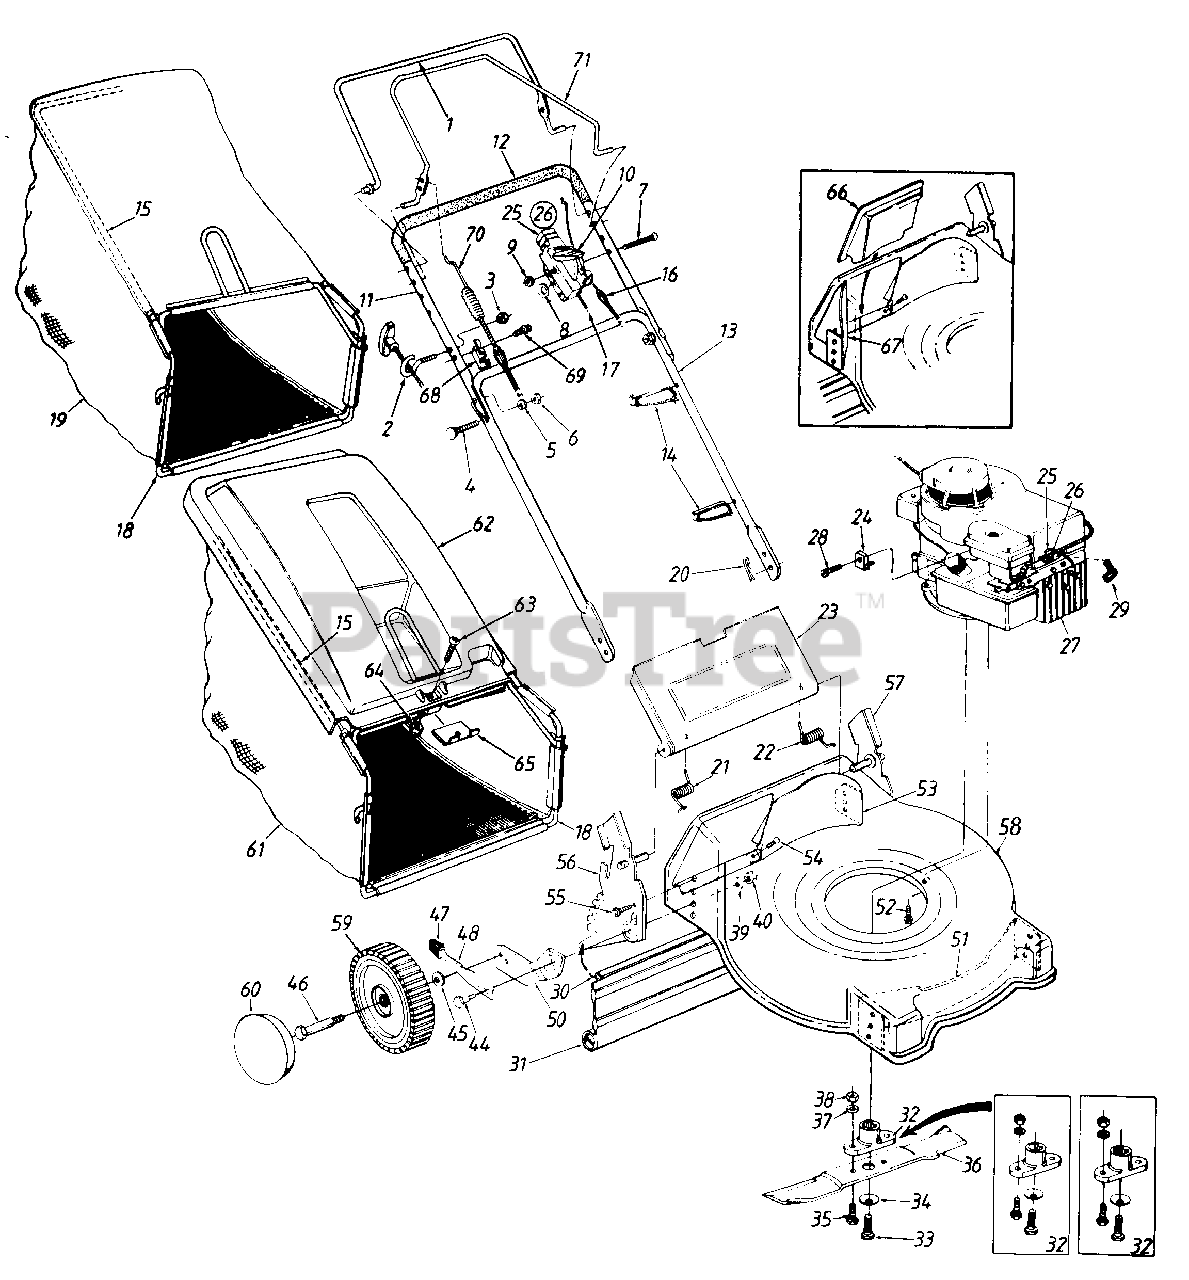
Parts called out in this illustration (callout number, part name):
2	Rope Guide Bolt
3	Hex L-Nut 1/4-20 Thd.
4	Curved Carr. Bolt 5/16-18 x 1.38" Lg.
5	L-Wash. 5/16" I.D.
6	Hex Nut 5/16-18 Thd.
7	Oval C-Sunk Mach. Scr.
8	Spr. Wash..66" I.D.
9	Hex L-Nut 1/4-20 Thd.
10	Throttle Lever
13	Lower Handle
14	Cable Tie
16	Control Cable - 39" (440R, 442R, 450R, 452R)
17	Throttle Control Wire - 51"
20	Int. Cotter Pin 5/16" Dia.
21	Door Spring - R.H.
22	Door Spring - L.H.
25	Throttle Body
26	Throttle Box Comp.
27	Engine
28	Hex Wash. Hd. Scr. #10-32 x .62" Lg.
29	Spark Plug Boot
30	Wire Rod
31	Rear Flap
32	Blade Adapter Kit
33	Hex Bolt 3/8-24 x 1.5" Lg.
34	Bell-Wash..39" I.D.
35	Hex Bolt 3/8-24 x 1" Lg.
36	21" Blade
37	L-Wash. 3/8" I.D.
38	Hex Nut 3/8-24 Thd.
39	Bell-Wash..39" I.D. x 1.38"
40	Hex Nut 3/8-16 Thd.
44	Shld. Bolt .5" Dia. x .357"
45	Bell-Wash..38" I.D. x .88" O.D.
46	Axle Bolt
47	Spring Lever Knob
48	Spring Lever
50	Pivot Bar
54	Torx Mach. AB-Tap Scr. 1/4 x .62" Lg
55	Hex L-Wash. Hd. AB-Tap Scr. 1/4 x .62" Lg.
56	Handle Brkt. Ass'y.- R.H.
57	Handle Brkt. Ass'y.- L.H.
60	Hub Cap
61	Grass Bags
62	Hard Top Cover
63	Pan Hd. Mach. Scr. 1/4-20 x .5" Lg.
64	Hex Nylon L-Nut 1/4-20 Thd.
68	Cable Mtg. Brkt.
69	Hex Wash. AB-Tap Scr. 5/16" x 75" Lg
70	S.P. Cable 44.75" Lg.
